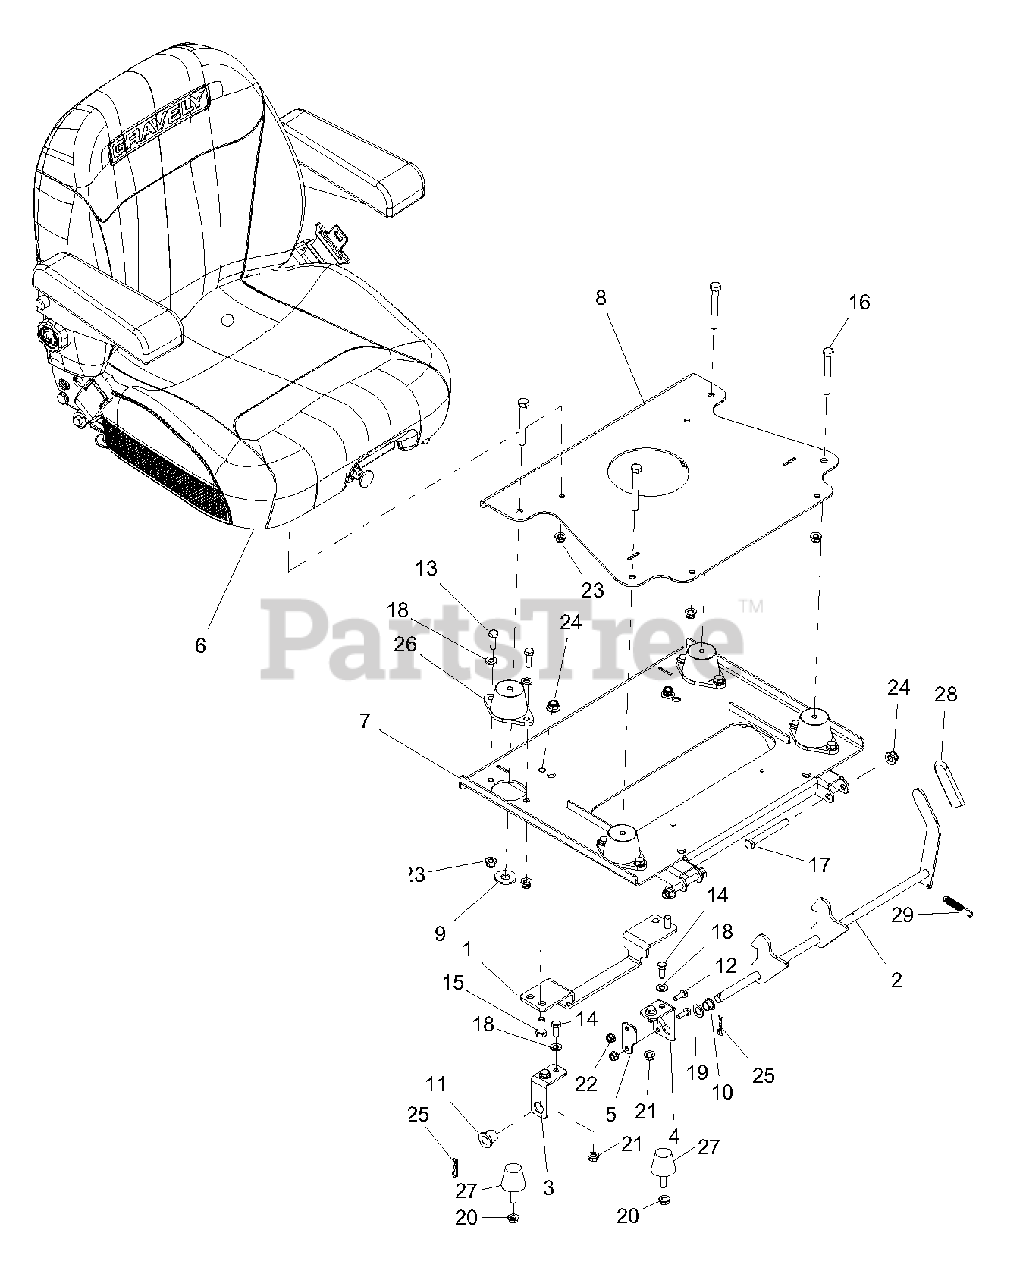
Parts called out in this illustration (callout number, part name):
1	BRKT, SEAT LATCH
2	WMT, SEAT LATCH
3	MOUNT, SEAT LATCH - RH
4	MOUNT, SEAT LATCH - LH
5	RETAINER-SEAT LATCH
6	SEAT, AIR SUSPENSION
7	WLDMT, SEAT ISO MOUNTING
8	WLDMT, SEAT MOUNTING
9	WLDMT, SEAT RETAINER
10	BSHG, SPLIT NYLON
11	BUSHING, FLANGE NYLON
12	BLT-HEX .25-20X.75 GR5 YWZC
13	BLT-HEX .31-18X1.00 GR5 YWZC
14	BLT-HEX .31-18X.75 GR5 YWZC
15	BLT-HEX .38-16X1.00 GR5 YWZC
16	BLT-HEX .38-16X3.0 GR5 FTD YWZ
17	BLT-HEX .38-16X3.25 GR5 YWZC
18	WSHR-FL-STL.344X.688X.065YWZC
19	WSHR-FL-STL .520X.827X.062 YWZC
20	NUT-SPNLK-FLG .312-18 YWZC
21	NUT, LK-TOP-FLG .312-18 YWZC
22	NUT, LK-TOP-FLG .25-20 YWZC
23	NUT-LK-NYL-FLG .31-18 YWZC
24	NUT-LK-NYL-FLG .38-16 YWZC
25	PIN-HAIR INT .08X.38X1.42 YWZC
26	MOUNT, ISOLATOR
27	BUMPER, STUD MOUNTED CONE SHAPED
28	GRIP-VINYL-YELLOW .125 x 1.0 x 3.0
29	SPRG, TENSION .043X.44X3.31 WLD 5.8
